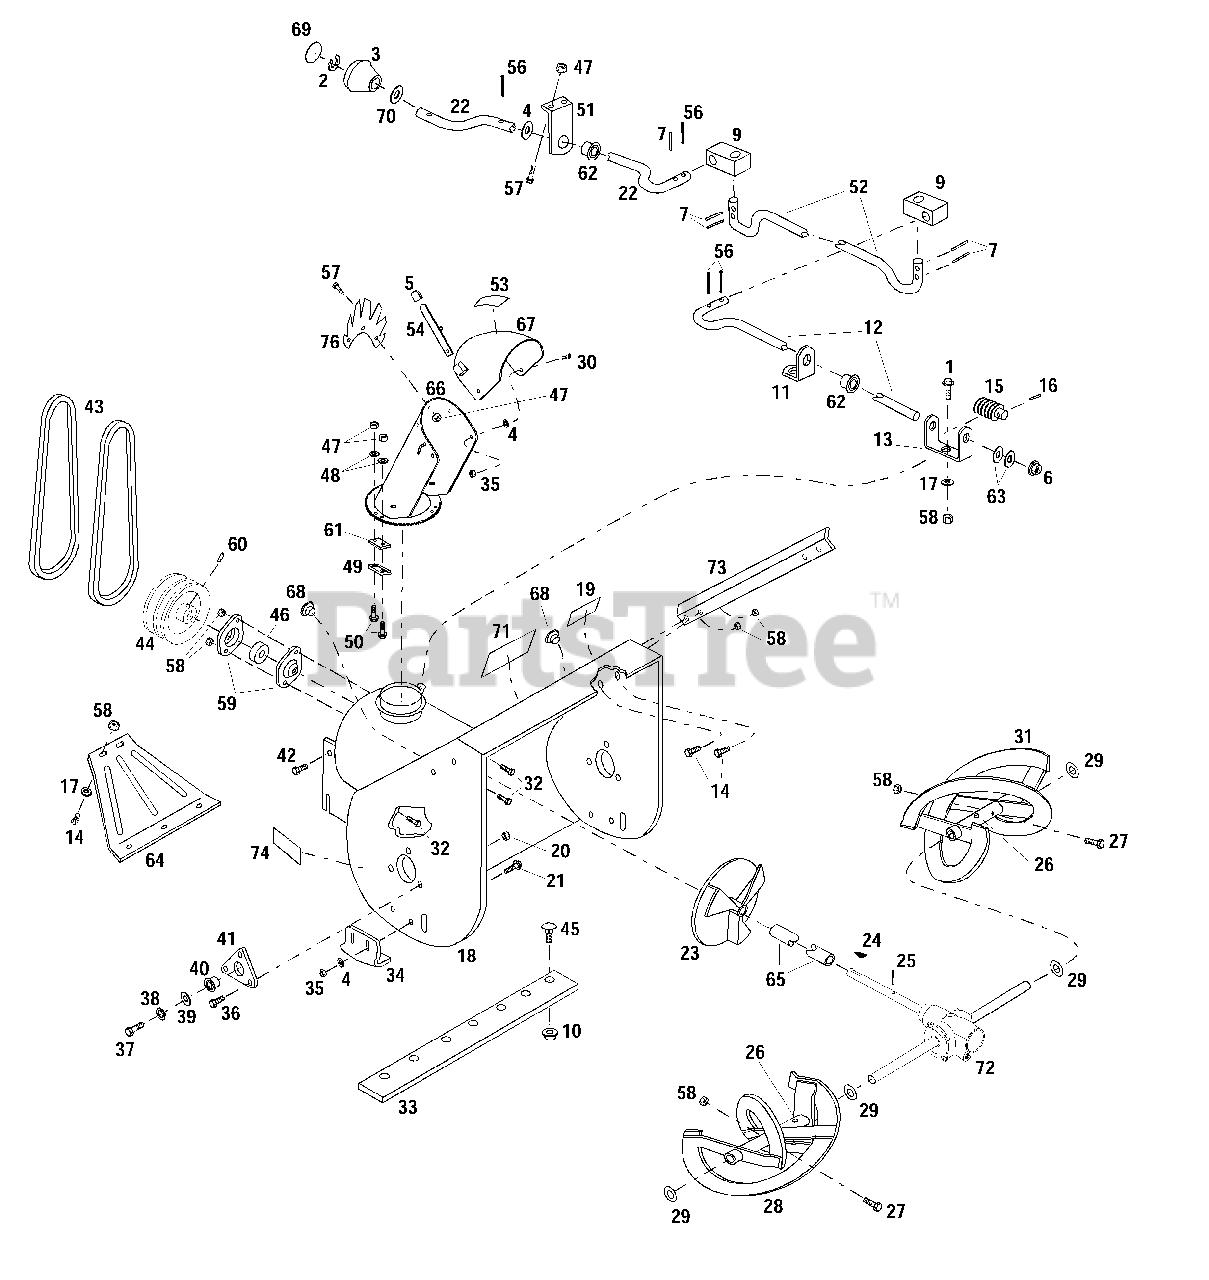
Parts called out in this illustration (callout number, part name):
1	Flange Bolt, 5/16-18 x 3/4
2	Retainer, 3/8
4	Flat Washer, 3/8
6	Flange Nut, 3/8-16
7	Roll Pin, 1/8 x 3/4
9	Swivel Block
10	Flange Nut, 5/16-18
11	Crank Support
12	Chute Control Shaft
13	Gear Support
14	Hex Head Cap Screw, 5/16-18 x 3/4
15	Worm Gear
16	Drive Pin, 3/32 x 3/4
17	Flat Washer, 5/16
18	Housing Assembly
19	Warning Decal
20	Lock Nut, 1/4-20
21	Carriage Bolt, 3/8-16 x 3/4
22	Chute Control Crank
23	Impeller Fan
24	Hy Pro Key, 3/16 x 3/4
25	Roll Pin, 1/4 x 1-1/4
26	Grease Fitting
27	Shear Bolt Kit
28	Auger, R.H.
29	Special Washer, 1-1/64
30	Hex Head Cap Screw, 3/8-16 x 3/4
31	Auger, L.H.
32	Carriage Bolt, 5/16-18 x 3/4
33	Scraper Blade
34	Skid Shoe
35	Lock Nut, 3/8-16
36	Hex Head Cap Screw, 1/4-20 x 5/8
37	Hex Head Cap Screw, 1/2-13 x 3/4
38	Lock Washer, 1/2
39	Flat Washer, 1/2
40	Flange Bearing
41	Bearing Support
42	Flange Bolt, 3/8-16 x 1/2
43	V-Belt
44	Auger Sheave
45	Carriage Bolt, 5/16-18 x 5/8
46	Ball Bearing
47	Lock Nut, #10-24
48	Flat Washer, #10
49	Hold-Down Clip
50	Sems Screw, #10-24 x 7/8
51	Chute Control Support
52	Chute Crank Rod
53	Warning Decal
54	Adjusting Lever
56	Cotter Pin, 3/32 x 1/2
57	Truss-Head Bolt, #10-24 x 3/8
58	Lock Nut, 5/16-18
59	Flange Bearing
60	Set Screw, 5/16-18 x 3/4
62	Nylon Bushing
63	Nylon Washer
64	Housing Support
65	Sleeve
66	Discharge Chute Assembly
67	Discharge Cap
68	Button Plug
69	Spun Silver Inlay
70	Flat Washer, 3/8
71	Housing Logo Decal
72	Gear Case Assembly
73	Drift Slicer (complete kit)
74	Housing Side Decal
76	Chute Deflector
